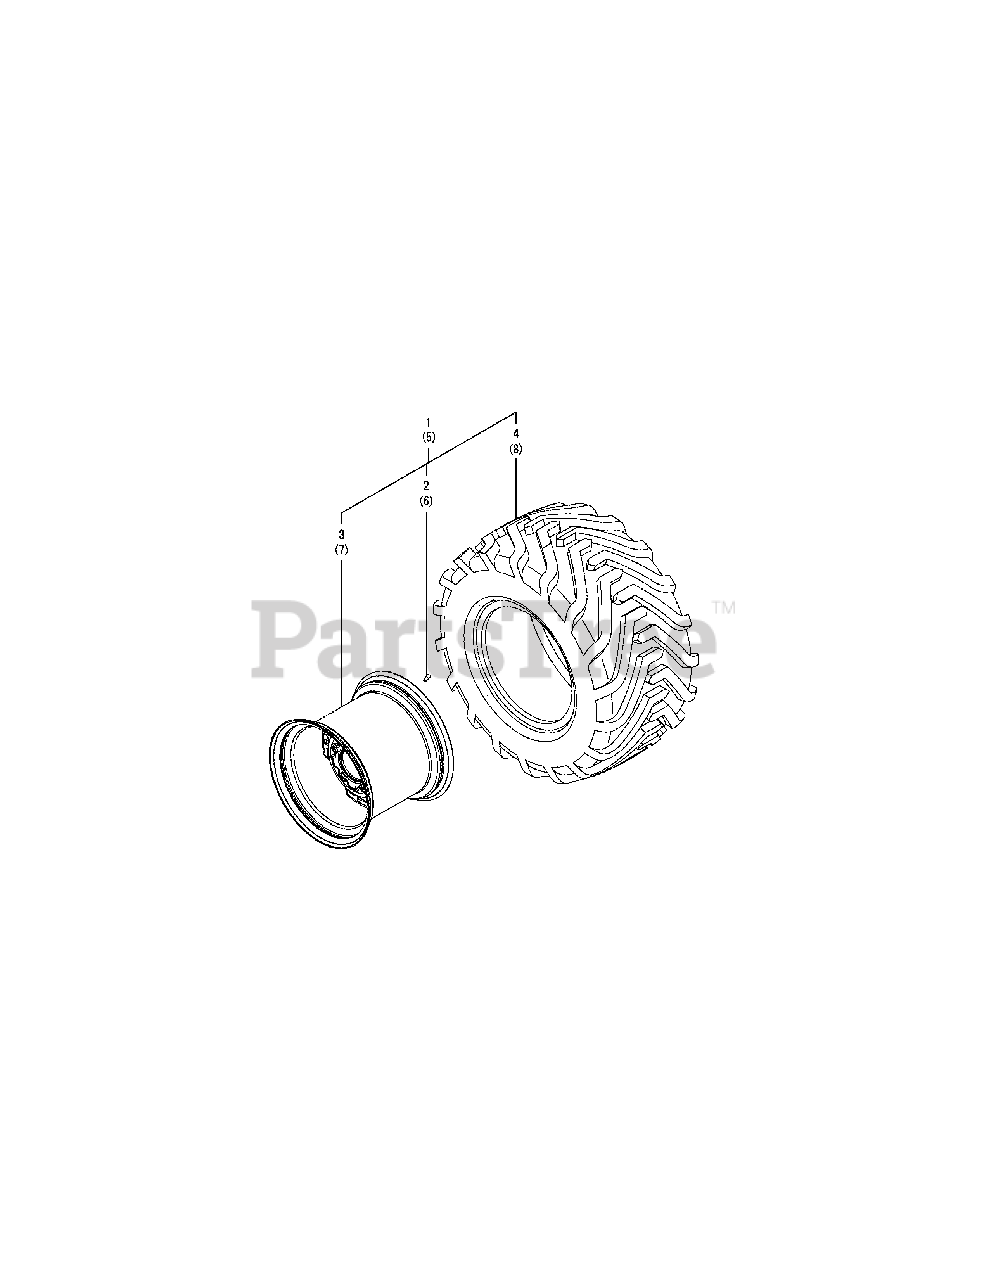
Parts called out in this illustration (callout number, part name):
1	R1 REAR TIRE L KIT
4	TIRE,26X12-12 R1
5	R1 REAR TIRE R KIT
8	TIRE,26X12-12 R1
